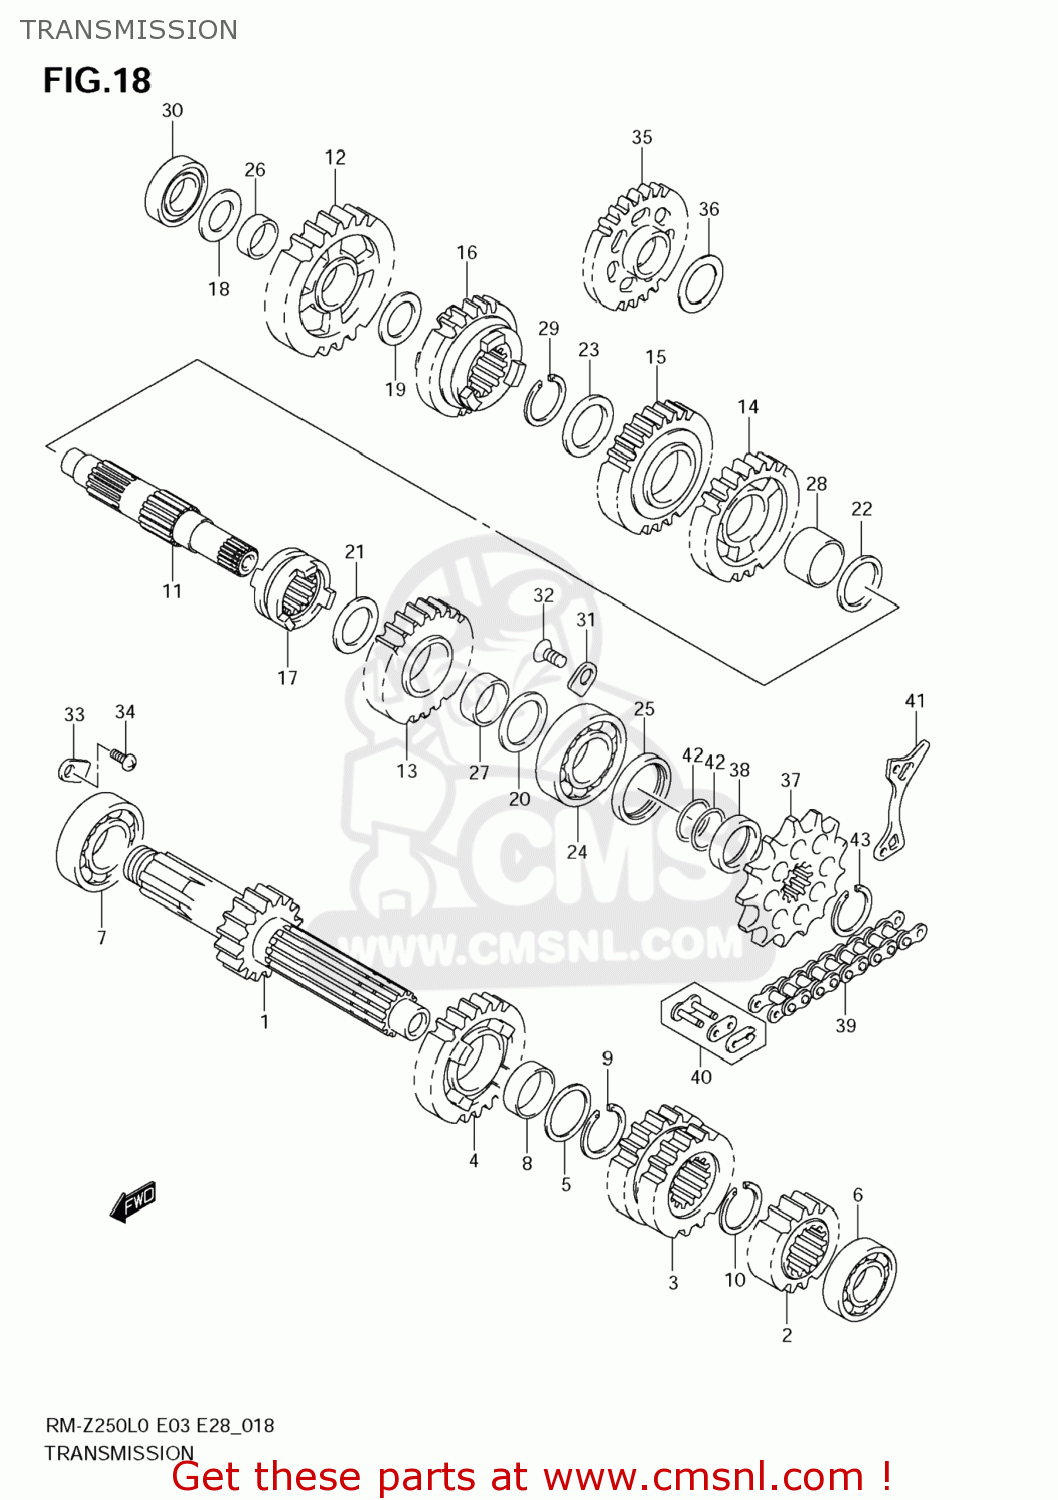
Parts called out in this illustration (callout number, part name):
1	SHAFT,COUNTER
2	GEAR,2ND DRIVE
3	GEAR,3RD & 4TH
4	GEAR,5TH DRIVE(NT:22)
5	SHIM(24X29X1)
6	BEARING(17X40X9.5)
7	BEARING(22X50X14)
8	BUSH(24X27X0.0)
9	CIRCLIP
10	CIRCLIP
11	SHAFT,DRIVE
12	GEAR,1ST DRIVEN(NT:28)
13	GEAR,2ND DRIVE
14	GEAR,3RD DRIVEN(NT:25)
15	GEAR,4TH DRIVEN(NT:26)
16	GEAR,5TH DRIVEN(NT24)
17	DOG,SLIDING
18	SHIM(17X28X1)
19	SHIM(20X28X1)
20	WASHER,2ND DRIVEN GEARL
21	SHIM(22X30X1)
22	SHIM(24X30X1)
23	SHIM(24X30X1)
24	BEARING(20X52X7.5)
25	SEAL,OIL(28X38X7.5)
26	BUSH(20X24X10)
27	BUSH(22X25X12)
28	BUSH(24X27X18)
29	CIRCLIP
30	BEARING(17X40X12)
31	RETAINER,COUNTER BEARING,R
32	SCREW(6X12)
33	RETAINER
34	BOLT(6X12)
35	GEAR,KICK STARTER IDLE
36	WASHER,KICK IDLE
37	SPROCKET,ENGINE
38	SPACER,ENGINE SPROCKET
39	CHAIN ASSY,DRI
40	JOINT SET,CHAIN
41	PLATE,FRONT CH
42	O RING(D:1.9,ID:19.8)
43	CIRCLIP
